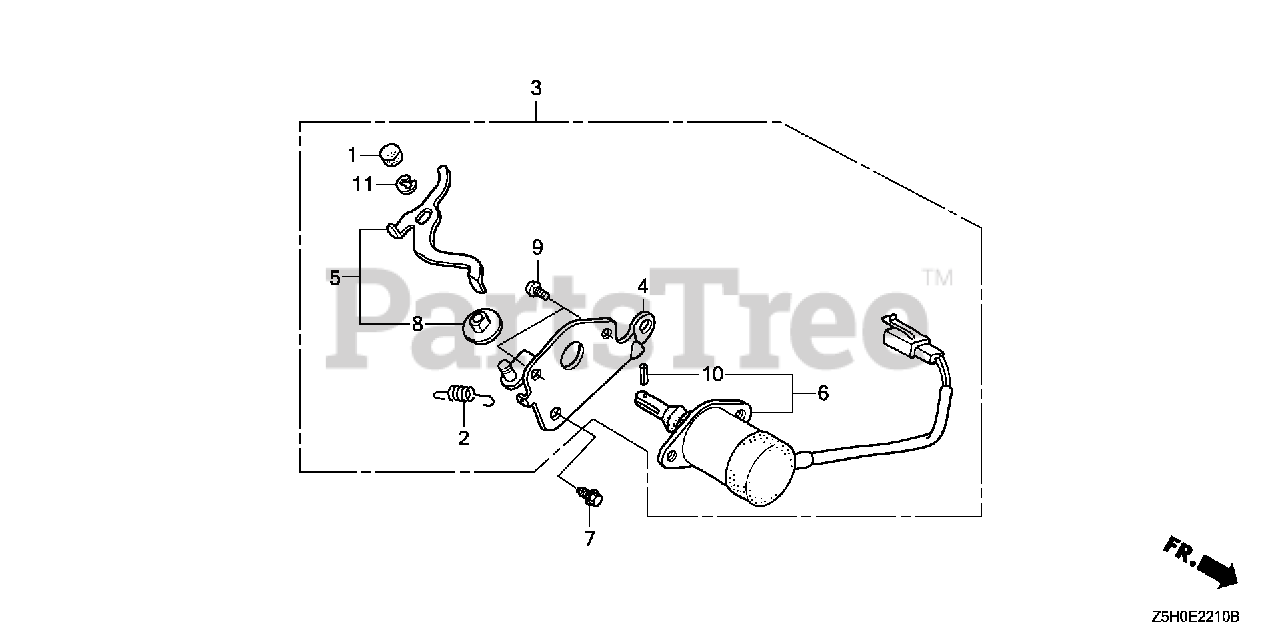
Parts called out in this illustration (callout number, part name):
1	CAP, CHOKE LEVER
2	SPRING, CHOKE RETURN
3	AUTO-THROTTLE ASSY.
4	STAY, SOLENOID THROTTLE
5	LEVER, SOLENOID THROTTLE
6	SOLENOID ASSY.
7	BOLT, FLANGE (6X12) (CT200)
8	BUSH, AUTO-THROTTLE LEVER
9	SCREW, PAN (5X8)
10	PIN, SPRING (2X6)
11	E-RING (4MM)
